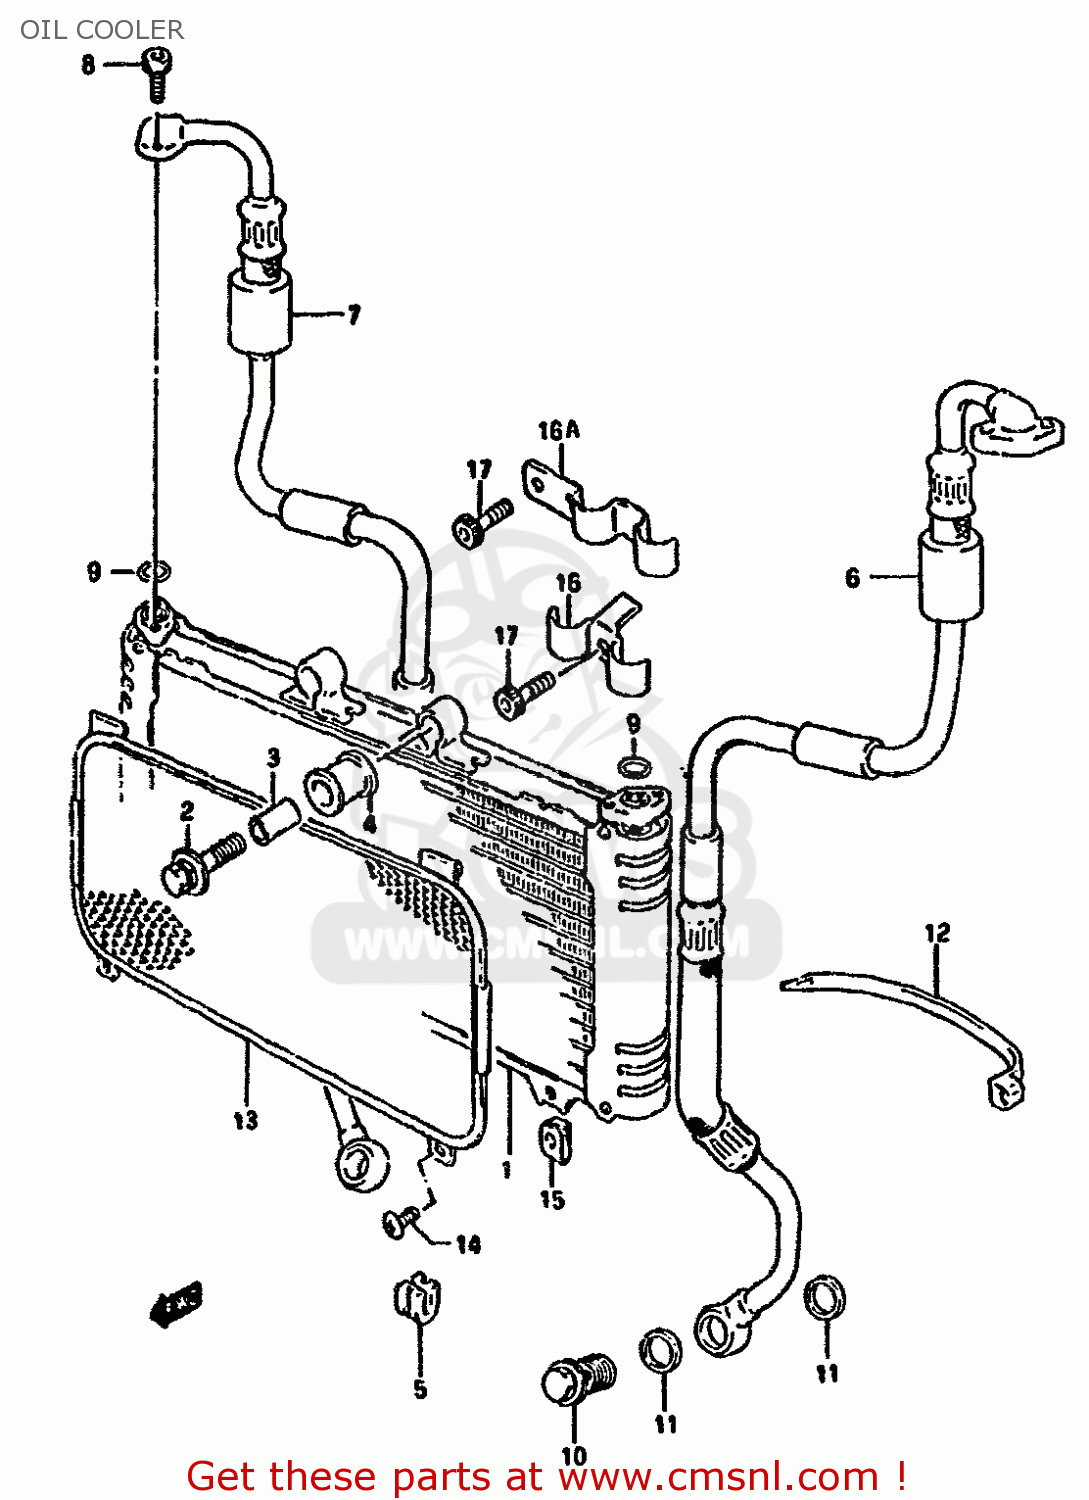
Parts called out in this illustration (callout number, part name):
1	COOLER,OIL
2	BOLT(8X40)
3	SPACER (8.8X12X24.5)
4	CUSHION,OIL COOLER NO.1
5	CUSHION,OIL COOLER NO.2
6	HOSE,OIL COOLER,L
7	HOSE COMP,OIL COOLER,RIGHT
8	BOLT
9	O RING(D:2.4,ID:12.3)
10	BOLT UNION
11	GASKET(16X22X2) (NAS)
12	CLAMP(L:235)
13	NET,OIL COOLER
14	SCREW
15	NUT
16	CLAMP,OIL HOSE
16A	CLAMP,OIL HOSE
17	BOLT
